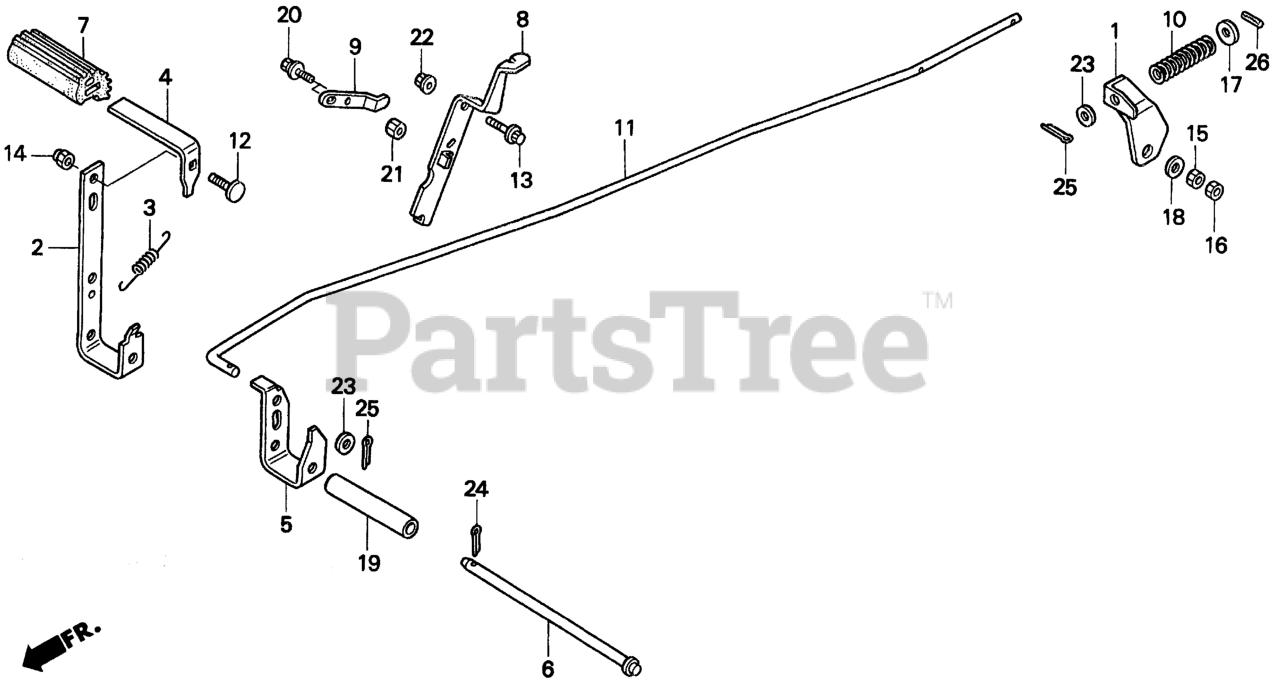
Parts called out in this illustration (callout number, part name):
1	ARM, RR. BRAKE
2	PEDAL, BRAKE & CLUTCH
3	SPRING, BRAKE PEDAL
4	BRACKET, BRAKE/CLUTCH
5	ARM, BRAKE
6	SHAFT, PEDAL
7	RUBBER, PEDAL
8	LEVER, PARKING BRAKE
9	SPRING, PARKING BRAKE LEVER
10	SPRING, BRAKE LOAD SETTING
11	ROD, RR. BRAKE
12	BOLT, SPECIAL (8X27)
13	BOLT, ADJUSTING ARM
14	NUT, FLANGE (8MM)
15	NUT, HEX. (5/16-24UNF)
16	NUT, HEX. LOCK UNJC (5/16-24)
17	WASHER, PLAIN (0.63)
18	WASHER (7/16X7/8X0.060)
19	COLLAR (13X7.5X89)
20	BOLT-WASHER (5X12)
21	NUT, HEX. (5MM)
22	NUT, FLANGE (8MM)
23	WASHER, PLAIN (10MM)
24	PIN, SPLIT (3.0X25)
24	PIN, COTTER (3.0X45)
25	PIN, SPLIT (4.0X22)
26	PIN, SPRING (4X25)
